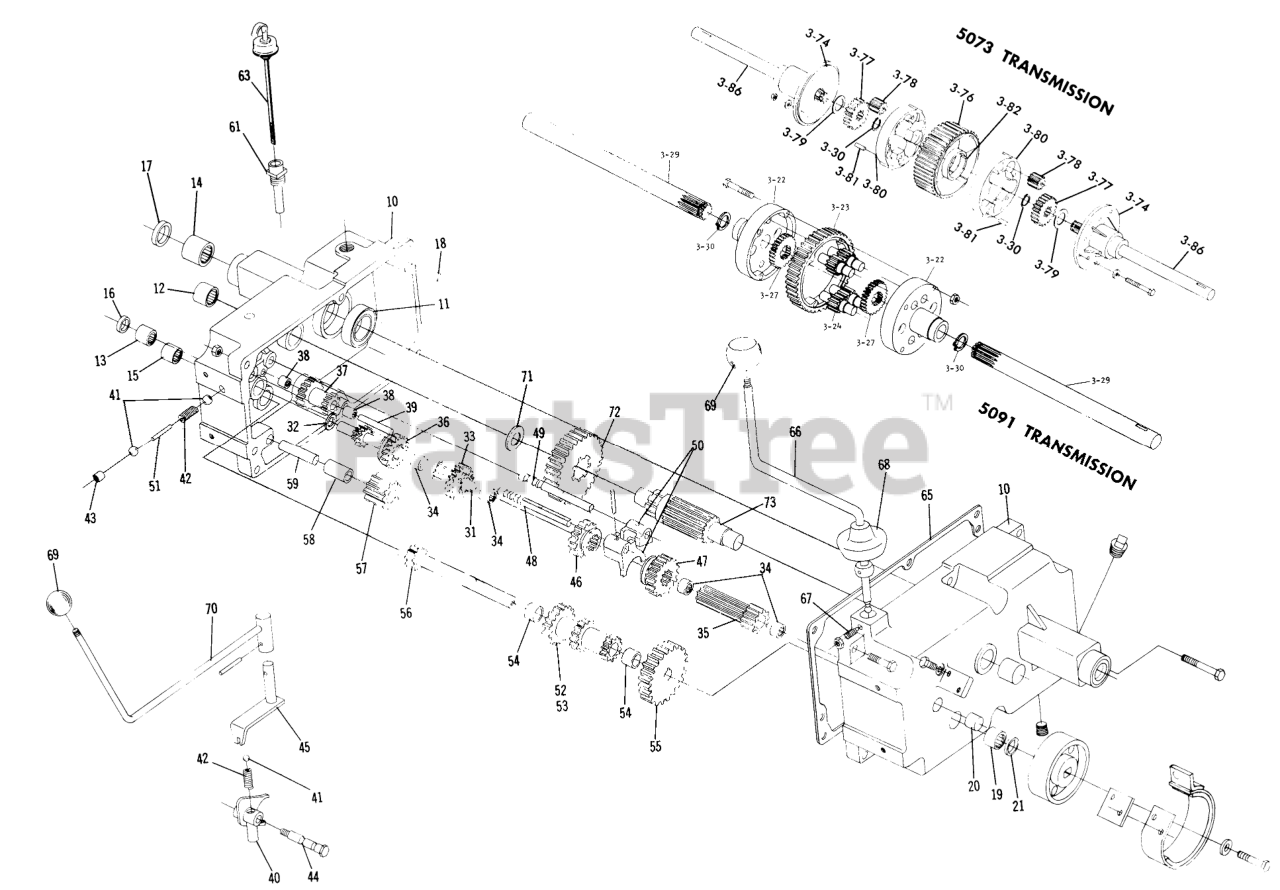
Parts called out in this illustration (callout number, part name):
3-12	BEARING-NEEDLE
3-13	BEARING-NEEDLE
3-15	BEARING-NEEDLE
3-16	SEAL-OIL
3-17	SEAL-OIL
3-18	PIN-DOWEL
3-19	BEARING-NEEDLE
3-21	SEAL-OIL
3-24	GEAR-PINION, 11T
3-27	GEAR-AXLE DIFFERENTIAL
3-31	SHAFT-INPUT
3-32	WASHER-THRUST
3-33	GEAR
3-34	BEARING-NEEDLE
3-35	GEAR
3-36	GEAR-SLIDING
3-38	BEARING-NEEDLE
3-39	GEAR-SHAFT REDUCTION
3-41	BALL-DETENT
3-43	CUP-PLUG
3-44	BOLT-DETENT
3-45	SHIFT ASM
3-46	GEAR-HI AND 2ND
3-47	GEAR-LOW AND REVERSE
3-48	RAIL-SHIFT
3-49	RAIL-REAR SHIFT
3-50	FORK-SHIFT
3-51	PIN-SHIFT
3-52	GEAR-CLUSTER
3-54	BUSHING-BRONZE
3-55	GEAR-CLUSTER SHAFT
3-57	GEAR/BUSHING ASM-REVERSE IDLER
3-58	BUSHING
3-59	PIN-DIFFERENTIAL
3-65	GASKET-TRANSMISSION
3-67	SETSCREW
3-68	COVER-DUST
3-69	SHIFT KNOB
3-71	WASHER-THRUST
3-73	PINION SHAFT
3-77	SIDE GEAR
3-80	BULLT 252
